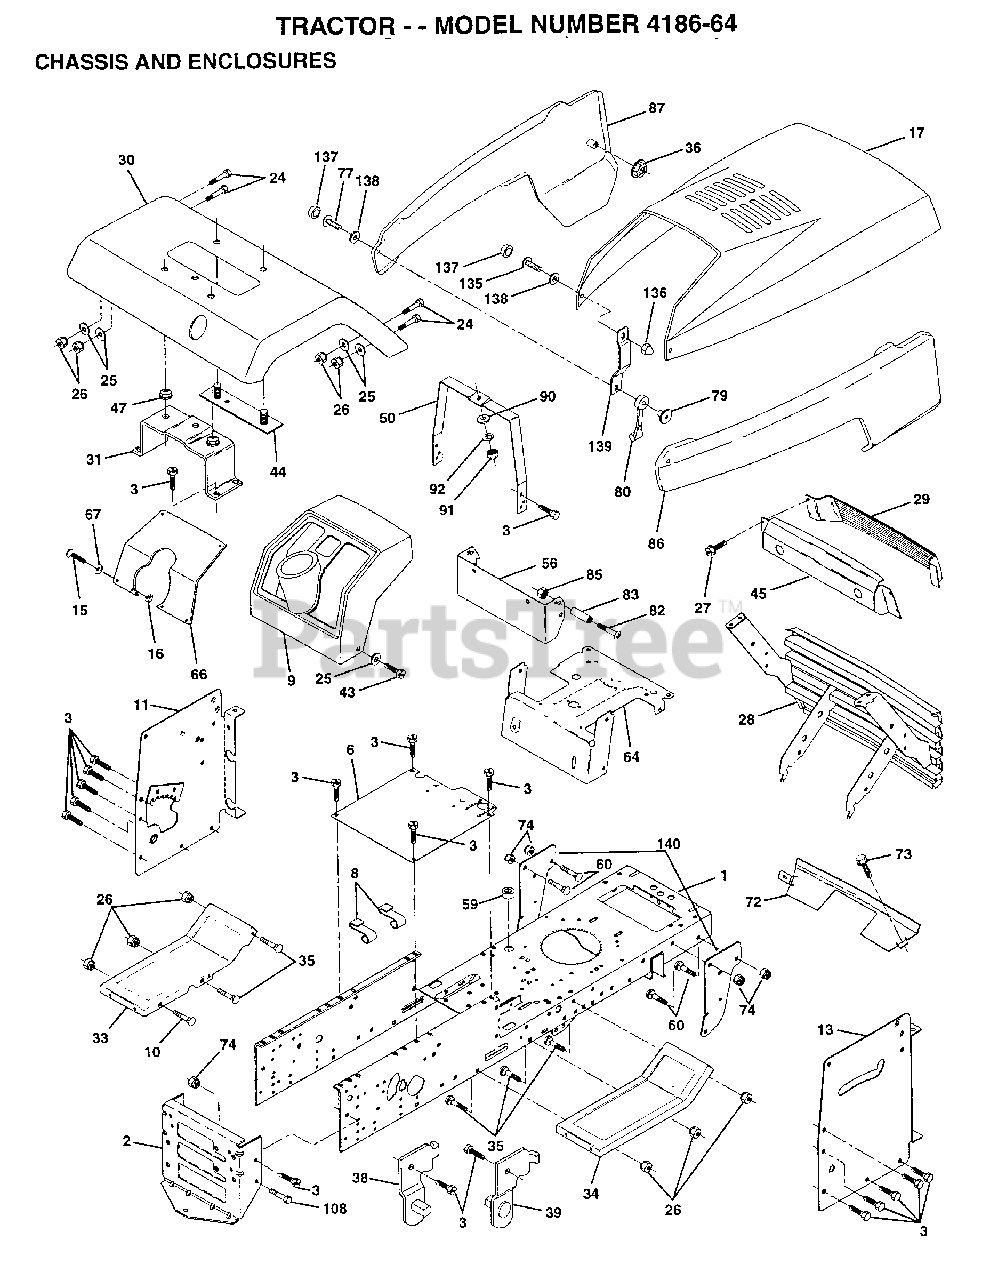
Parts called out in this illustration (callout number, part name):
1	CHASSIS WLDMT 11G
3	SCREW
8	"CLIP,INSULATOR"
9	DASHBOARD BLACK
11	PANEL.DASH.LH.PNT
13	PANEL.DASH.RH.PNT
15	SCREW
24	BOLT
25	WASHER
26	NUT
28	GRILLE ASM PNT
29	LENS.BAR.CLEAR
31	BRKT.ASM.FENDER
33	FOOTREST.LH.LT/GT
34	FOOTREST.RH.LT/GT
35	BOLT
36	PAL NUT LT
38	BRACKET ASM LH
39	BRACKET ASM RH
43	SCREW
44	STRAP ASM FENDER
45	BEZEL.ASM.
47	NUT-PUSH YT
50	DASH.SUPT.YP/HUSQ
56	EXT DASH LTYT
60	BOLT
64	DASH.LOWER.LT
66	PLATE SLKSCR YP
67	WASHER
72	STRAP.GRILLE.424
73	SCREW CRT
77	SCREW
79	WELDNUT
80	HOOD LATCH T
82	SCREW
83	SPACER LT
86	PANEL ASM SIDE RH
87	PANEL ASM SIDE LH
90	WASHER PM
92	LOCKWASHER
135	SCREW.10-24X3/8.
136	ACORN NUT RB
137	SNAP CAP LT
138	WASHER LT
139	BKT.SPT.HOOD/PANL
